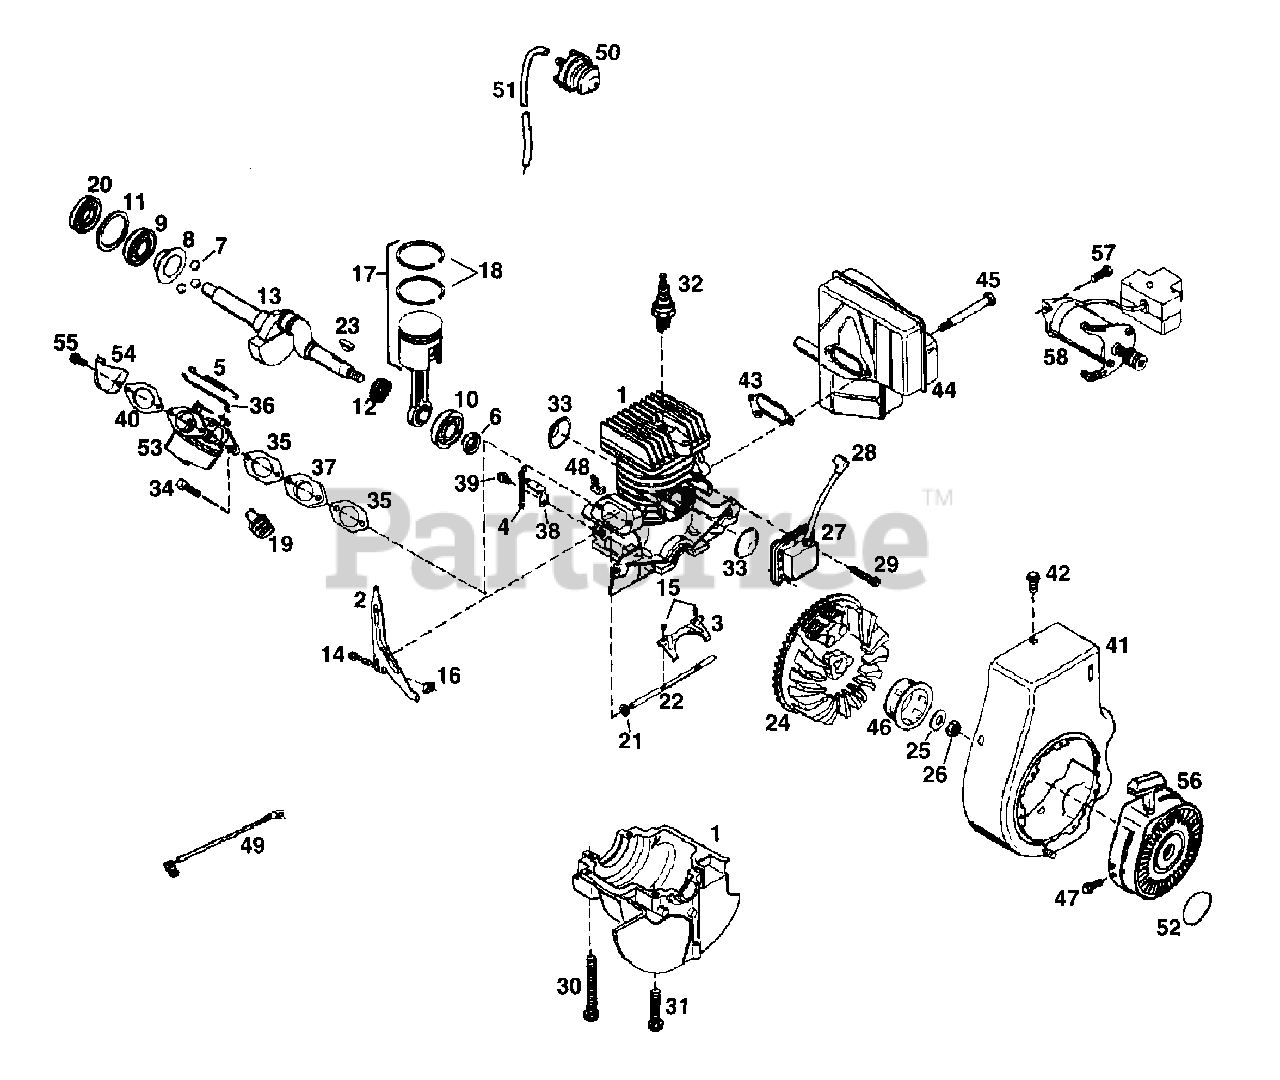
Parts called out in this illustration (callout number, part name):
1	Cylinder Ass'y
2	Governor Lever
3	Governor Lever
4	Extension Spring
5	Throttle Link Spring
7	Ball Bearing
8	Slide Ring
9	Ball Bearing
10	Ball Bearing
11	Bearing Retainer
12	Bearing Strip (31 Needles)
13	Crankshaft
14	Screw, 10-32 x 3/4"
15	Screw, 4-40 x 1/4"
16	Lock Nut, 10-32
17	Piston & Rod Ass'y
19	Control Knob
22	Governor Shaft
23	Flywheel Key
25	Bell Washer
26	Flywheel Nut
27	Solid State Ignition
28	Spark Plug Cover
29	Screw, Torx T 15, 10-24 x 15/16"
30	Screw, 5/16-18 x 2-3/16"
31	Screw, 5/16-18 x 1-5/8"
32	Resistor Spark Plug
33	Port Cover
34	Screw, 5/32 Allen, 1/4-20 x 5/8"
35	Carburetor Gasket
36	Governor Link
38	Control Lever
39	Screw, 8-32 x 1/2"
40	Air Cleaner Gasket
41	Blower Housing
42	Screw, 5/16-18 x 5/8"
43	Exhaust Gasket
45	Screw, 5/16-18 x 3-13/64"
46	Starter Cup
47	Screw, 8-20 x 21/64"
48	Wire Clip
49	Wire Harness
50	Primer Ass'y
51	Primer Line
52	Starter Decal
53	Carburetor
55	Screw, Torx T 25, 10-32 x 3/8"
56	Rewind Starter
57	Screw, Torx T 30, 1/4-20 x 1/2"
58	Electric Starter
